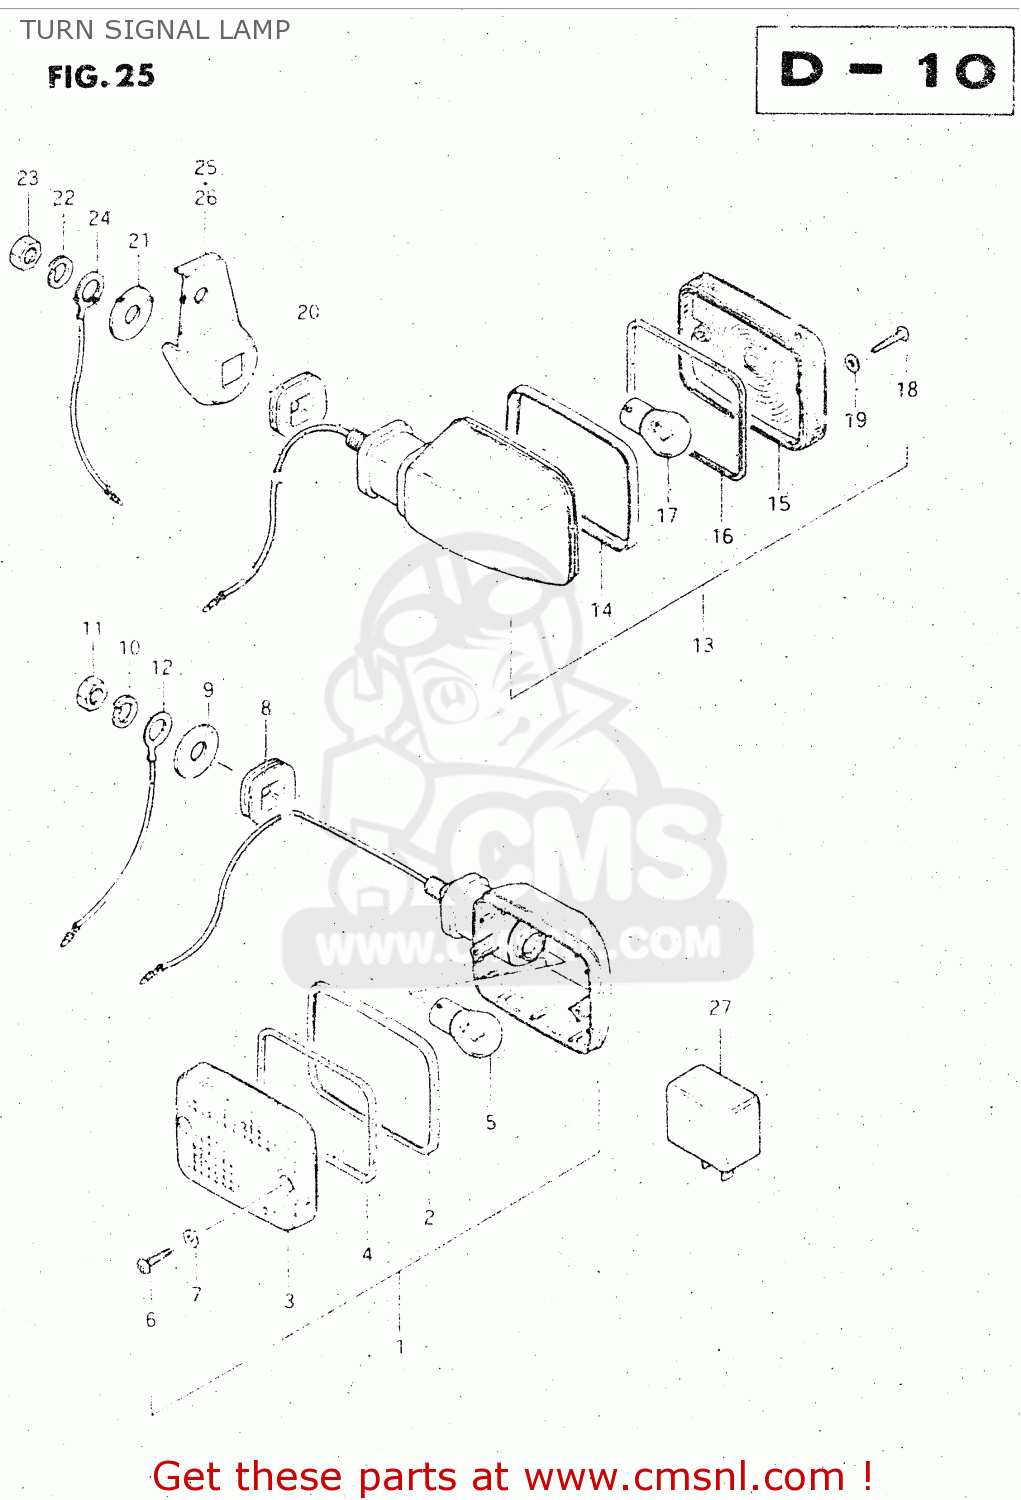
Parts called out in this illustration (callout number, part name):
1	LAMP ASSY,FR TURN SIGNAL
2	RIM
3	LENS
4	GASKET (NAS)
5	BULB 12V 21W
6	SCREW
7	GASKET (NAS)
8	CUSHION
9	WASHER (10.5X30X2.3)
10	LOCK WASHER
11	NUT
12	WIRE
13	LAMP, REAR TURN SIGNAL
14	RIM
15	LENS
16	GASKET (NAS)
17	BULB 12V 21W
18	SCREW
19	GASKET (NAS)
20	CUSHION
21	WASHER (10.5X30X2.3)
22	LOCK WASHER
23	NUT
24	WIRE
25	BRACKET,REAR TURN SIGNAL
26	BRACKET,REAR TURN SIGNAL
27	RELAY,TURN SIGNAL
